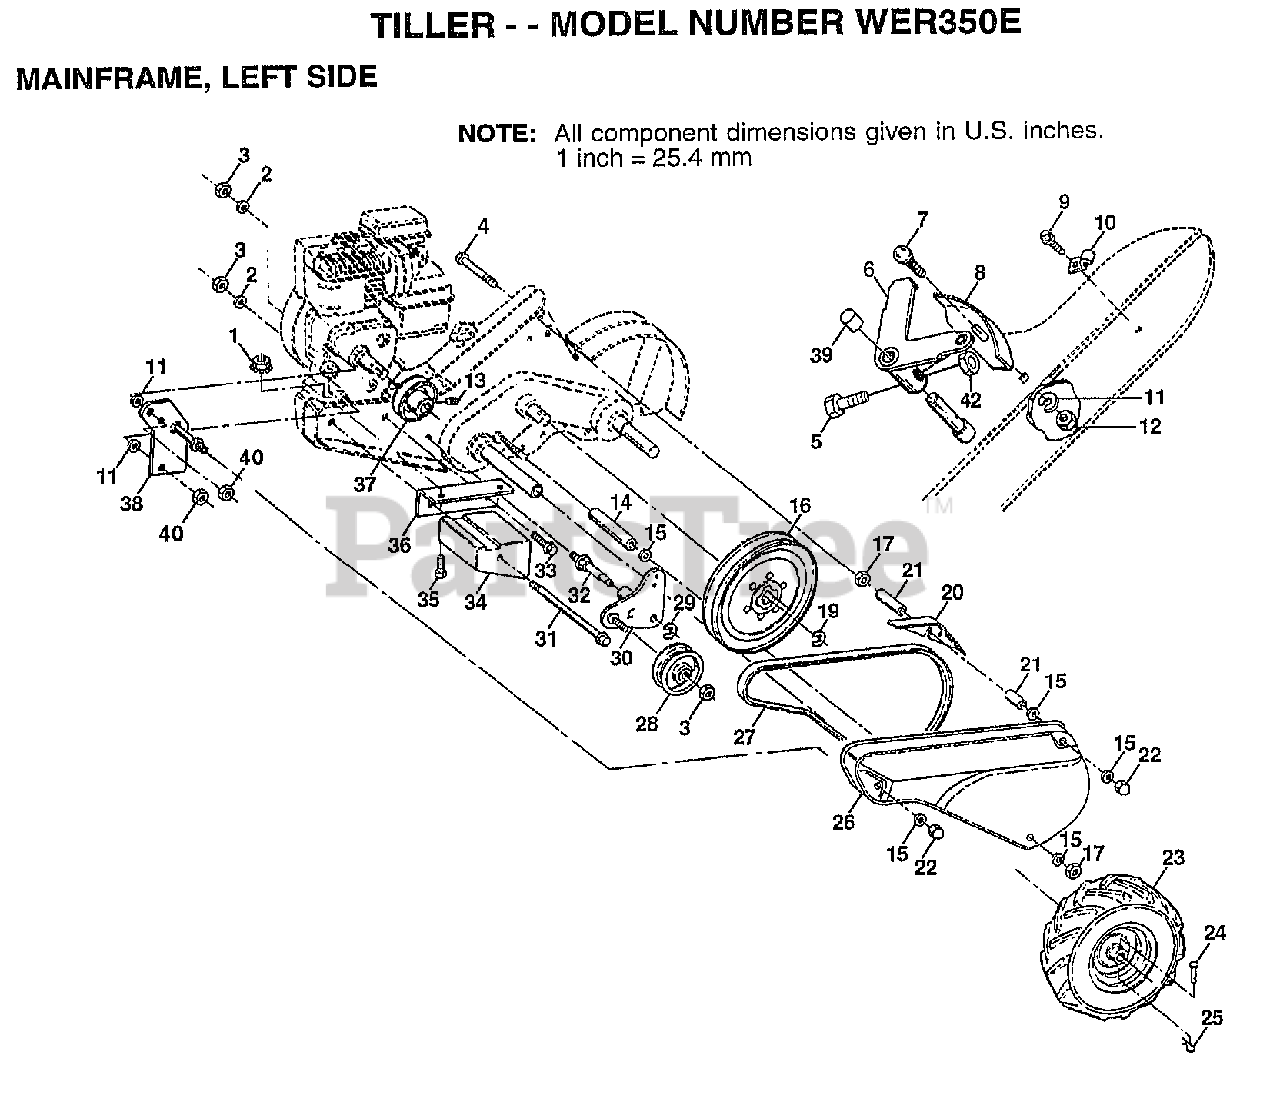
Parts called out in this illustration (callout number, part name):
2	LOCKWASHER
3	NUT.HEX.3/8-16UNC
4	BOLT TI
5	"SCREW-LEVER,SHI"
6	LEVER ASM CRT
7	BOLT
8	PANEL TI
10	CONDIUT CLIP T
11	LOCKWASHER
13	SET SCREW
14	SPACER
15	WASHER
16	SHEAVE.TRANS.
17	NUT.HEX.5/16-18
20	GUARD CRT
21	SPACER.SPLIT
22	NUT TI
23	TIRE.CHV.13X5.0-6
24	RIVET.DRILL.1.75
26	GUARD.BELT.PNT.
27	BELT-V
28	PULLEY-IDLER TI
29	KLIP RING
30	BRACKET ASM IDLER
31	BOLT CRT
32	SHIFT ARM CRT
33	BOLT
34	COUNTERWEIGHT CRT
35	BOLT.HEX.5/16-1.5
36	BRACKET LH CRT
37	ENGINE SHEAVE
38	BELT GUARD BRKT
39	CAP PLUNGER BLACK
40	NUT
42	LOCKNUT
